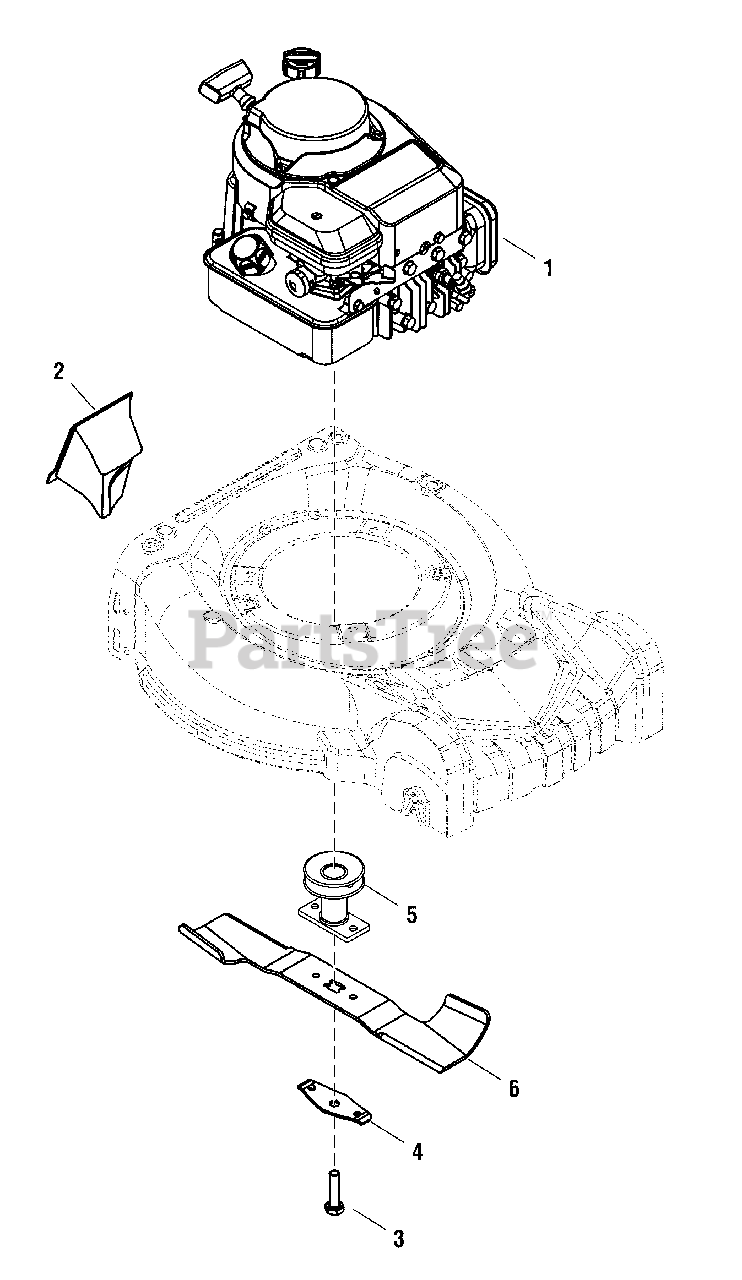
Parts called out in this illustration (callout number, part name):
1	* ENGINE, Briggs & Stratton, Mod. 122S02-0007-H1
2	MULCH PLUG
3	SCREW Hex, 3/8-24 x 1-1/2
4	SUPPORT, Blade Bell
5	BLADE ADAPTER
